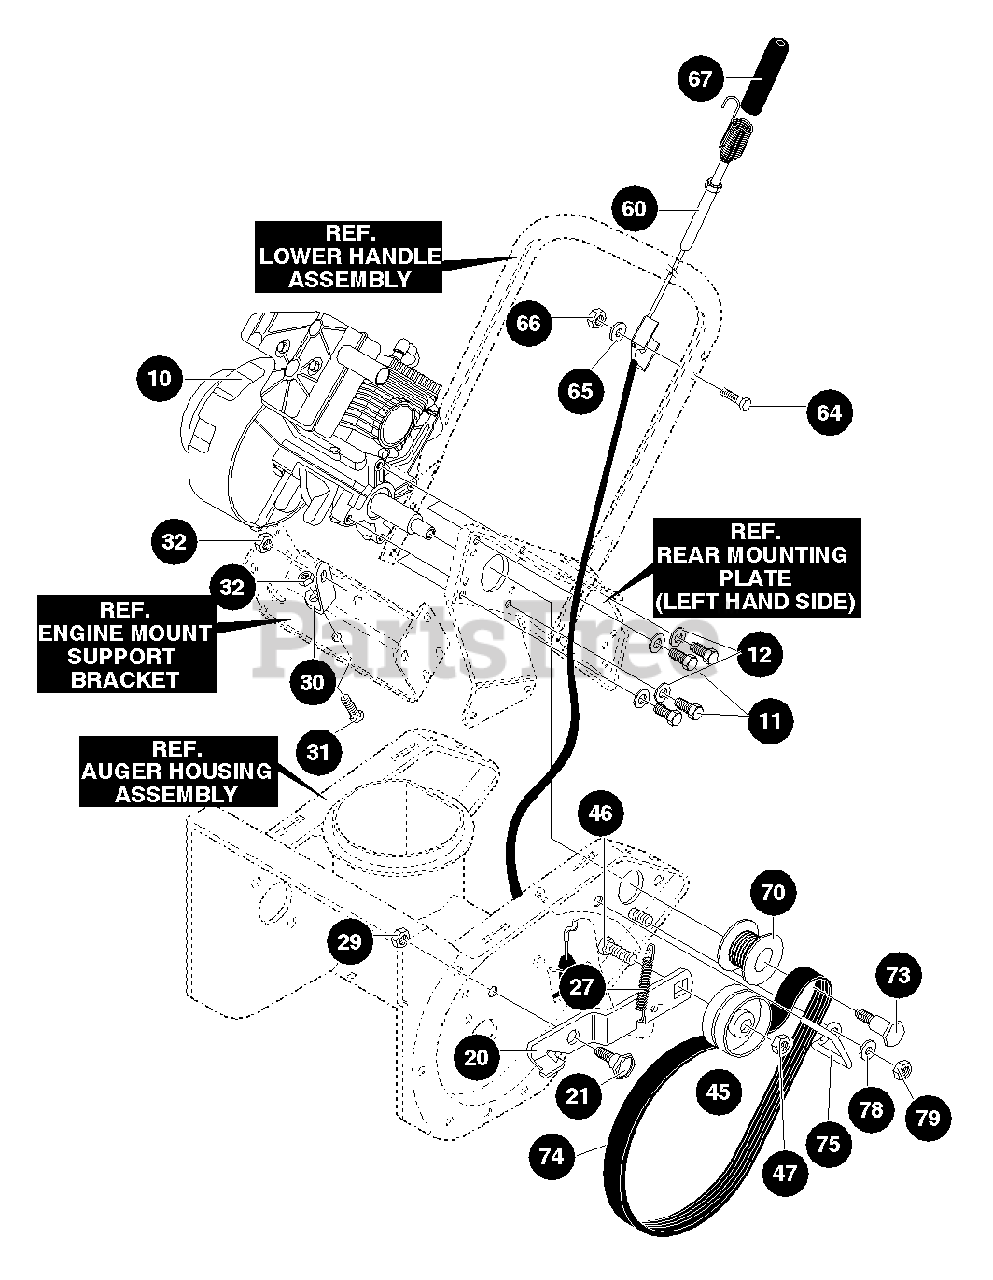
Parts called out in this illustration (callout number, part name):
10	5HP
11	SCREW, 5/16-18 X .75
12	WASHER, .328 X .60 X .09
20	BRACKET, IDLER ARM
21	SH. BOLT 5/16-18
27	SPRING, IDLER BRAKE
29	NUT, 5/16-18 RGHXCTRLK
30	SUPPORT, ENGINE
31	SCREW 5/16-18 X .50
32	NUT, 5/16-18 REGHXCTRLK
45	PULLEY, IDLER
46	CARR. BOLT, 3/8-16 X 1.50
47	NUT, 3/8-16 CTRLKJAM
60	CABLE, DRIVE CONTROL
64	SCREW 1/4-20 X 1.50
65	FLATWASHER
66	NUT, 1/4-20 RGHXCTRLK
67	COVER, CABLE SPRING
70	PULLEY, 4. 5HP POLY V
73	SH. BOLT .625 X .282
74	BELT, POLY
75	GUIDE, BELT
78	FLATWASHER
79	NUT, 5/16-18 REGHXCTRLK
